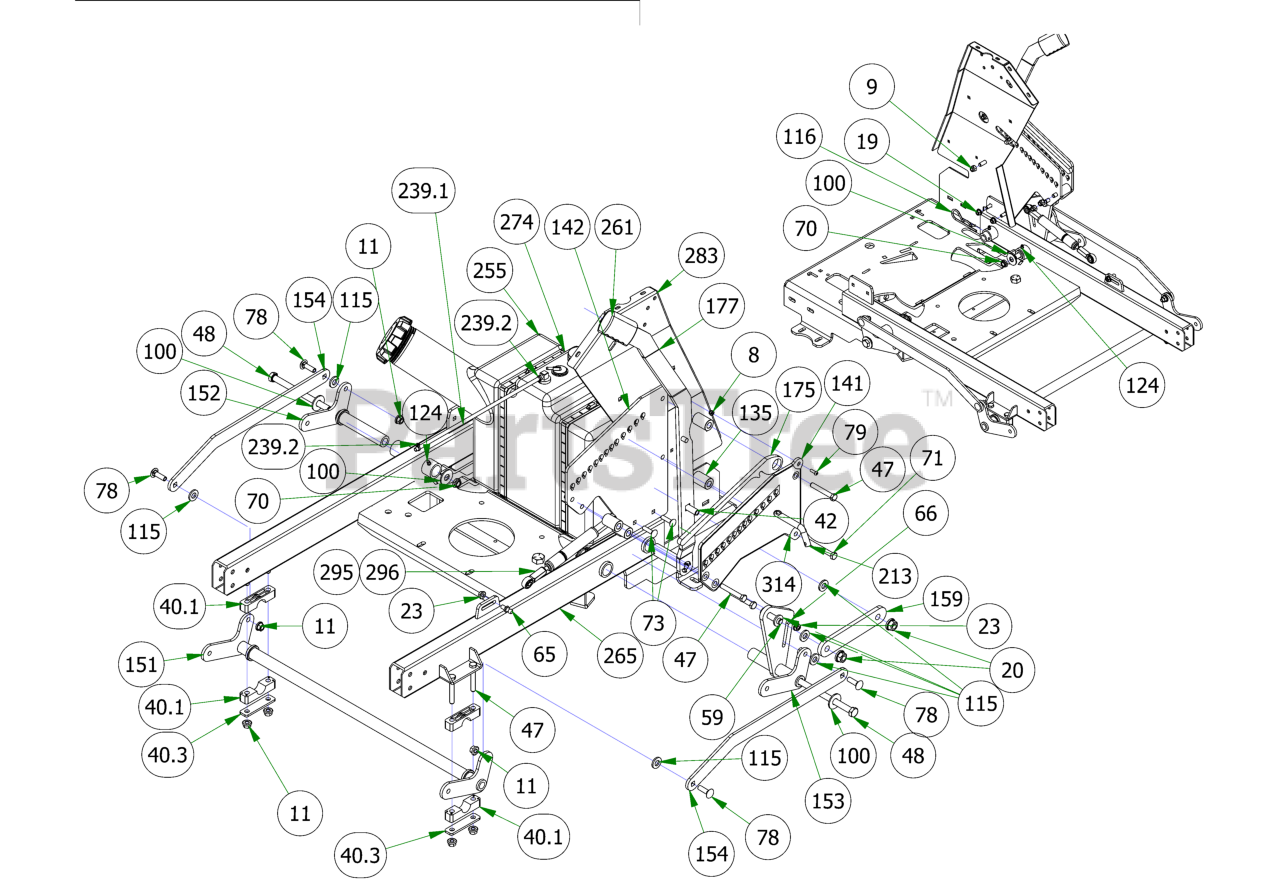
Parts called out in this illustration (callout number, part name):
8	10-24 NYLON INSERT LOCKNUT ZINC
9	3/8-16 NYLON INSERT LOCKNUT ZINC
11	3/8-16 NYLON INSERT FLANGE LOCKNUT (GR.F) ZINC
19	5/16-18 NYLON INSERT FLANGE LOCKNUT ZINC
20	1/2-13 NYLON INSERT FLANGE LOCKNUT ZINC
23	5/16-18 HEX SERRATED FLANGE NUT HARD/ZINC
40	Pillow Block Kit
40.1	Pillow Block MZ
40.3	Pillow Block Strap
42	1/2-13 X 1-1/2 CARRIAGE BOLT (GR.5) ZINC
47	3/8-16 X 2-1/2 HEX CAP SCREW (GR.5) ZINC
48	1/2-13 X 6 1/2 HEX CAP SCREW (GR.5) ZINC
59	1/2-13 x 1 3/4" GR5 Hex Bolt
65	10mm Damper Ball Stud-Steering
66	10mm Damper Ball Stud-XP Linkage
70	1/2-13 NYLON INSERT JAM LOCKNUT ZINC
71	3/8-16 X 3 HEX CAP SCREW (GR.5) ZINC
73	5/16-18 X 1-1/4 CARRIAGE BOLT ZINC
78	3/8-16 X 1-1/4 CARRIAGE BOLT ZINC
79	10-24 X 5/8 BUTTON SOCKET CAP SCREW 18-8 STAINLESS STEEL
100	1/2 F/W USS (1-3/8" OD) ZINCC
115	.505 ID X 1.000 OD X .125 THICK FLAT WASHER NYLON
116	Revolt Cotter Pin for 7/8" to 1" shank
124	1/4 DRIVE-TYPE STRAIGHT GREASE FITTING (NO BALL) ZINC
135	.502 ID X .750 OD X 1.500 Long Spacer
141	Outer Adjustment Plate 2019 Stand On
142	Inner Adjustment Plate 2019 Stand On
151	Revolt Front Actuator Bar Weldment Black
152	Rear Actuator Bar Weldment - RH
153	Rear Actuator Bar Weldment - LH Black
154	Revolt Actuator Linkage - BLACK
159	Lever Secondary Linkage Revolt Black
175	2019 Stand On Deck Lever Lock
177	2019 Stand On Deck Lift Lever Welded Assembly
213	Height Adj Pin
239	15" Revolt Fuel Line Assembly
239.1	1/4" Fuel Line Hose
239.2	1/4 Fuel Hose Clamp
255	2019 REVOLT FUEL TANK
261	2019 Stand On Lift Grip
265	2019 Stand On Frame
274	2019 Stand On Gas Tank Strap
283	LH Podium Panel
295	200 lb Gas Spring- 54" Deck outlaw
296	250lb Gas Spring - 61" Deck
314	2022 Revolt Deck Height Decal
